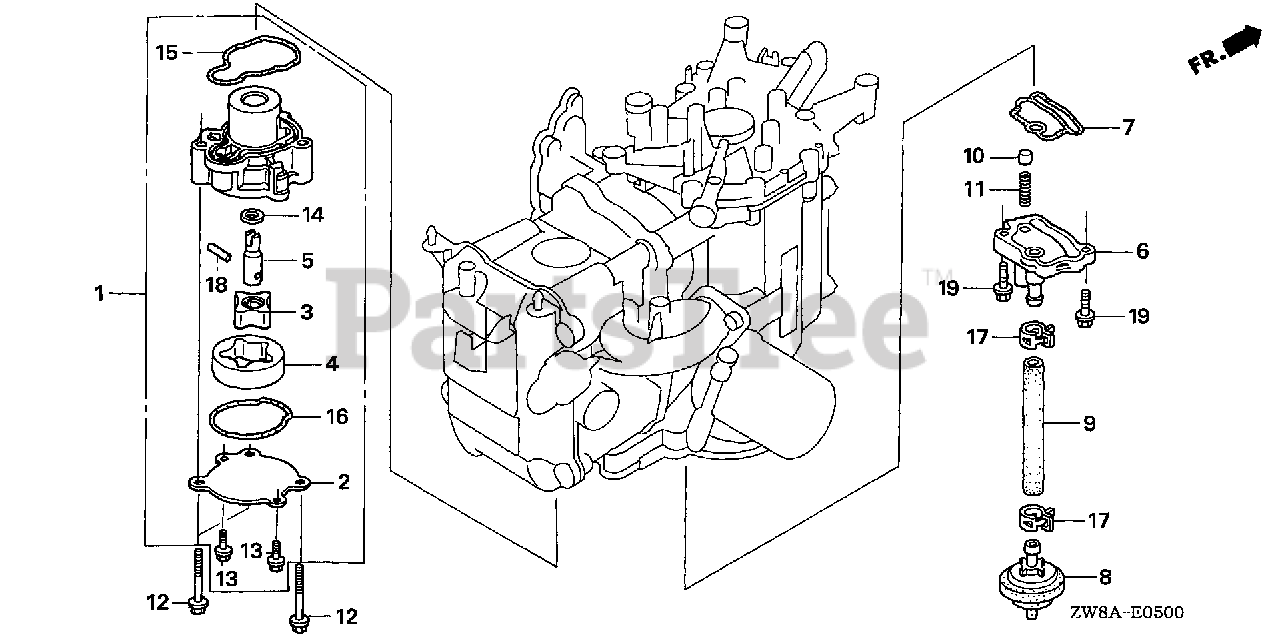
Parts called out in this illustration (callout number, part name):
1	PUMP ASSY., OIL
2	COVER, OIL PUMP
3	ROTOR (INNER)
4	ROTOR (OUTER)
5	SHAFT, OIL PUMP
6	FLANGE, OIL STRAINER
7	O-RING, OIL STRAINER FLANGE
8	STRAINER, OIL
10	VALVE, CHECK
11	SPRING, CHECK VALVE
12	BOLT, FLANGE (6X35)
13	BOLT, FLANGE (5X12) (CT200)
14	WASHER, THRUST (11MM)
15	O-RING, OIL PUMP
16	O-RING, PUMP COVER
17	CLAMP, TUBE (D17)
18	ROLLER (4X15.8)
19	BOLT, FLANGE (6X22)
